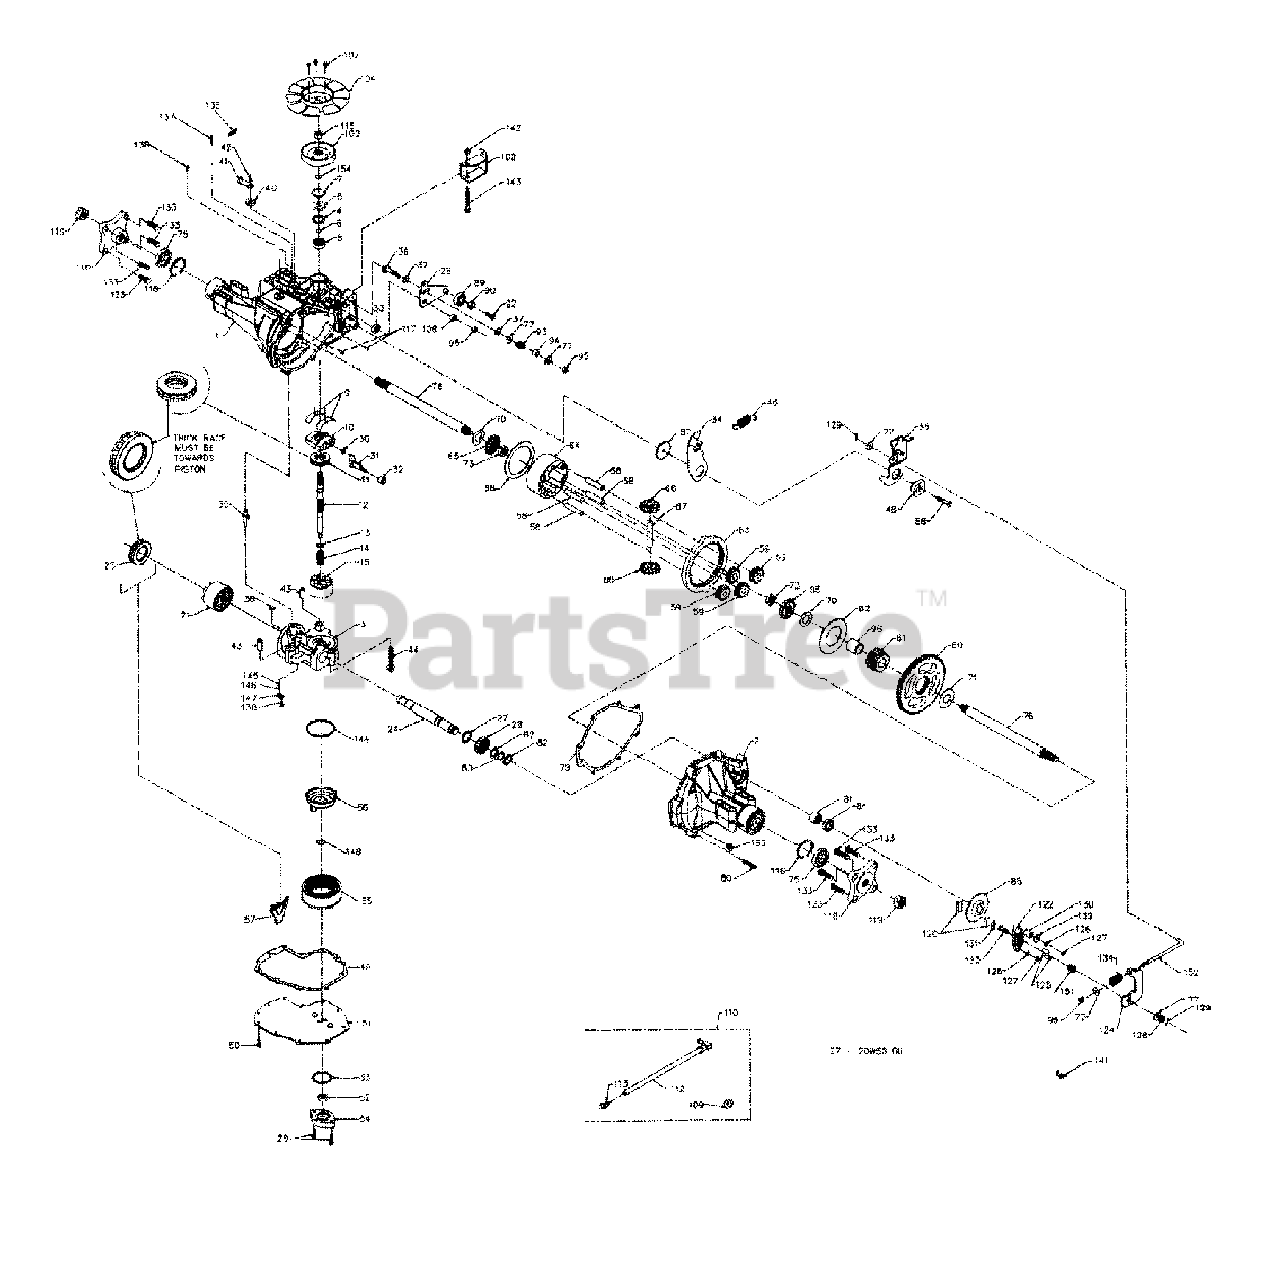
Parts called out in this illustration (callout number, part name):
1	Main Housing Ass'y.
2	R.H. Housing Ass'y.
3	Center Section Ass'y.
6	Wire Retaining Ring
7	Retaining Ring
8	Ball Bearing
9	Cradle Bearing
10	Variable Swashplate
11	Thrust Bearing
13	Block Thrust Washer
15	Cylinder Block Ass'y.
21	Cylinder Block Ass'y.
24	Output Shaft
25	Thrust Bearing
28	16T Pinion Gear
29	Capscrew M6 x 1-20
31	Trunnion Arm
32	Trunnion Bushing
35	Actuating Arm
36	Stud 5/16-24 Thd.
37	Friction Puck
38	Bypass Plate
39	Bypass Actuator
42	Retaining Ring
46	Neutral Spring
48	Adjusting Spring
49	Lower Gasket
50	Self-Tapping Screw
52	Gerotor Ass'y.
54	Gerotor Cover
55	Filter
56	Charge Manifold
57	Retainer, Motor Bearing
58	Pin, Carrier
59	15T Planet Gear
60	67T Spur Gear
61	21T Sun Gear
62	Planet Thrust Plate
63	51T Ring Gear
64	Planetary Carrier
67	Shaft, Differential
68	Differential, Thrust Plate
73	Hex Jam Nut 5/8-18 Thd.
75	Seal
77	Washer
79	Gasket, Main Housing
80	Torx Hd. Scr. 5/15-18 Thd.
81	Needle Bearing
83	Retaining Ring
88	Screw 5/16-24 x 1.75" Lg.
90	Spacer, Locating
92	Countersunk Screw
95	Hex L-Nut 5/16-24 Thd.
96	Sleeve Bearing
97	Oil (.91 Gal.)
102	Torque Bracket
103	Pulley
106	Spacer, Trunnion
109	Vent Bushing
112	Hose Fitting Ass'y.
113	Cap-Vent Ass'y.
116	Retaining Ring
118	Hub
119	Hex Nut 3/4-16 Thd.
120	Puck, Brake
123	Bolt, Square Head
125	Pin, Brake
126	L-Wash. 1/4" I.D.
127	Hex Nut 1/4-20 Thd.
128	Castle Nut
129	Cotter Pin
131	Puck Plate
134	Brake Spring
136	Extension Spring
138	Screw, Self-Tapping 10-32 x .5"
139	Washer .265" I.D. x .875" O.D.
141	Spring, Brake
142	Hex L-Nut 5/16-18 Thd.
143	Bolt 5/16-18 x 2.5" Lg.
145	Relief Spring
147	Plate, Relief
151	Brake Comp. Spring
152	Brake Pull Rod
154	Wire Retaining Ring
